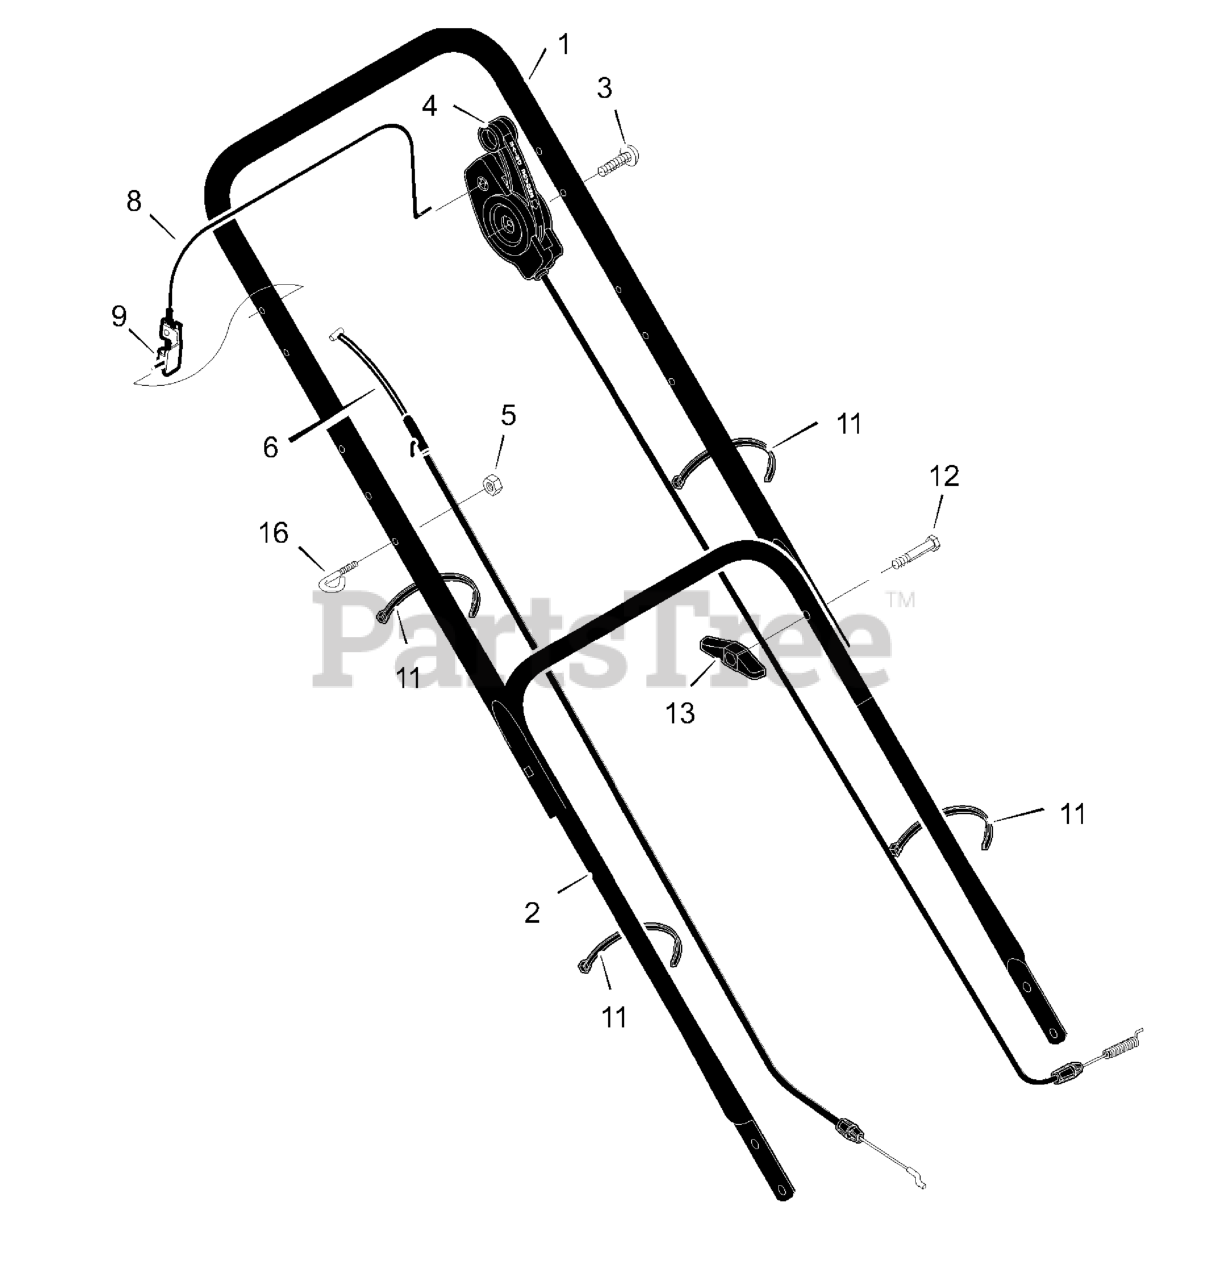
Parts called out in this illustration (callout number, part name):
1	Handle, Upper (Black)
2	Handle, Lower (Black)
4	Control, Drive
5	Locknut
6	Cable, Stop
8	Lever, Stop
9	Bracket, Stop Lever
11	Fastener, Cable
13	Knob
16	Guide, Rope
